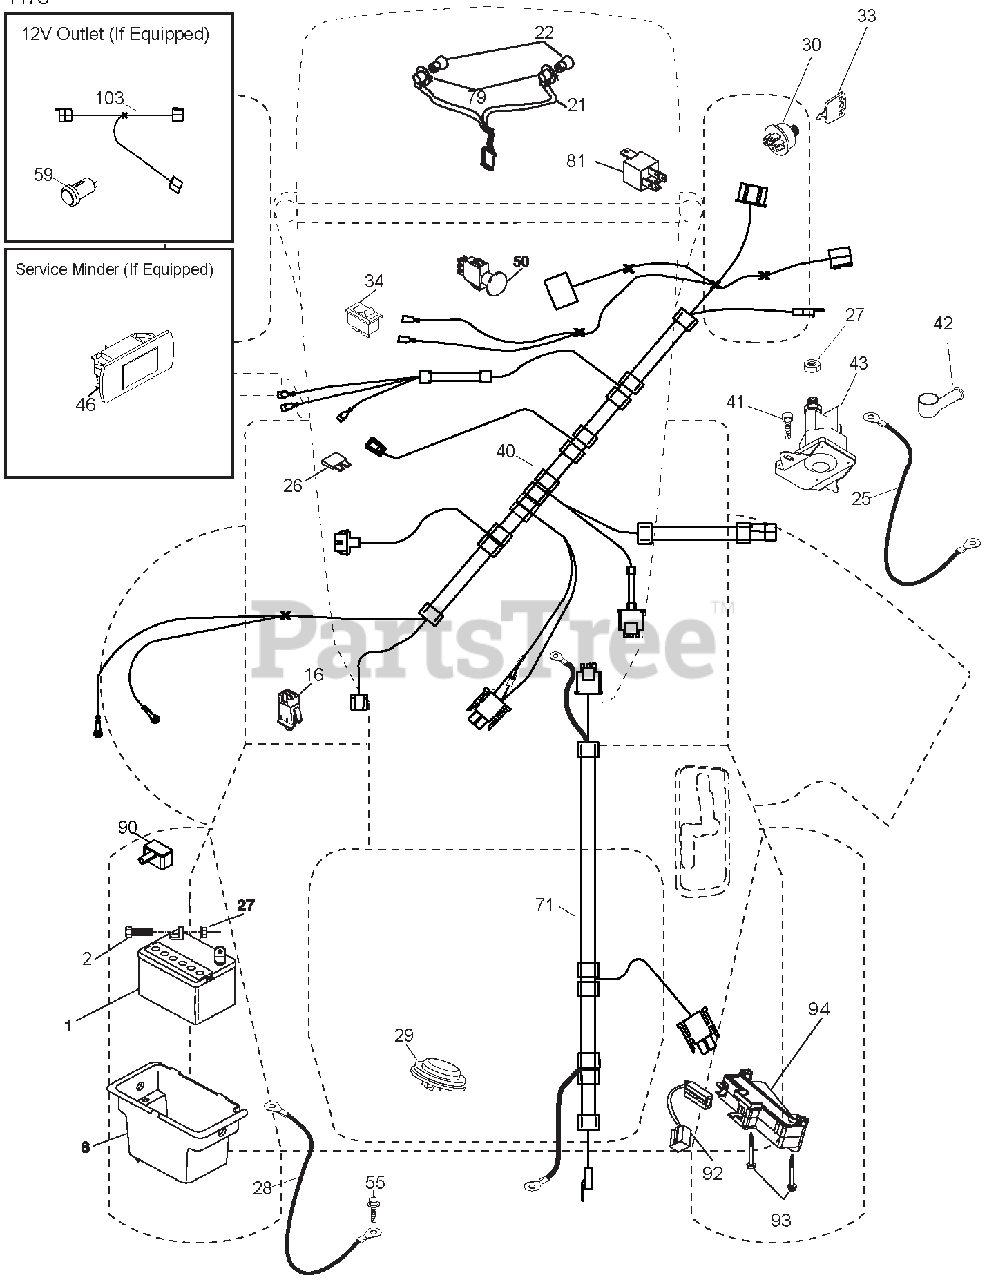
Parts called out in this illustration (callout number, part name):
1	BATTERY.12.VOLT.28.AMP.WET
2	BOLT.HEX.HD.1/4-20UNC X 3/4
8	BOX.BATTERY.MNT.REAR.LT.TEX.BL
16	SWITCH.INTERLOCK.NONO.GRAY
21	HARNESS ASM.LIGHT.22"(4152J)
22	BULB.LIGHT.#1156
25	CABLE.STARTER
26	FUSE.20 AMP.
27	Nut, Keps Hex 1/4-20 unc
28	CABLE.BLACK.22"REAR BATT.TEX
29	SWITCH.SEAT.DELTA.OPC.9LB.
30	SWITCH.IGN.DLTA.P-IN.ROS
33	KEY/CHAIN.BLISTER PACK.GEN.USA
34	SWITCH.LIGHT/RESET.B/B/RED.
40	HARNESS IGN. ELECTRIC RELAY
41	Screw 1/4-20 x 1/2
42	COVER.TERMINAL.RED
43	SOLENOID.W/BRASS PLUNGER.2005
46	HOUR METER
50	SWITCH.PTO.8 TERMINAL.BLACK
55	SCREW.5/16-18X3/4.SMGML.TAP/R
71	HARNESS.IGN.CHASS.TEX.REAR.BAT
79	SOCKET ASM.BULB.TWISTLOCK
81	RELAY HARNESS SEALED
90	COVER TERMINAL BATTERY FR. TEX
92	HARNESS.PIGTAIL.CONSLE.ROS.MLK
93	SCREW.PLASTITE.10-14 X 2.0
94	MODUAL REVERSE ROS
